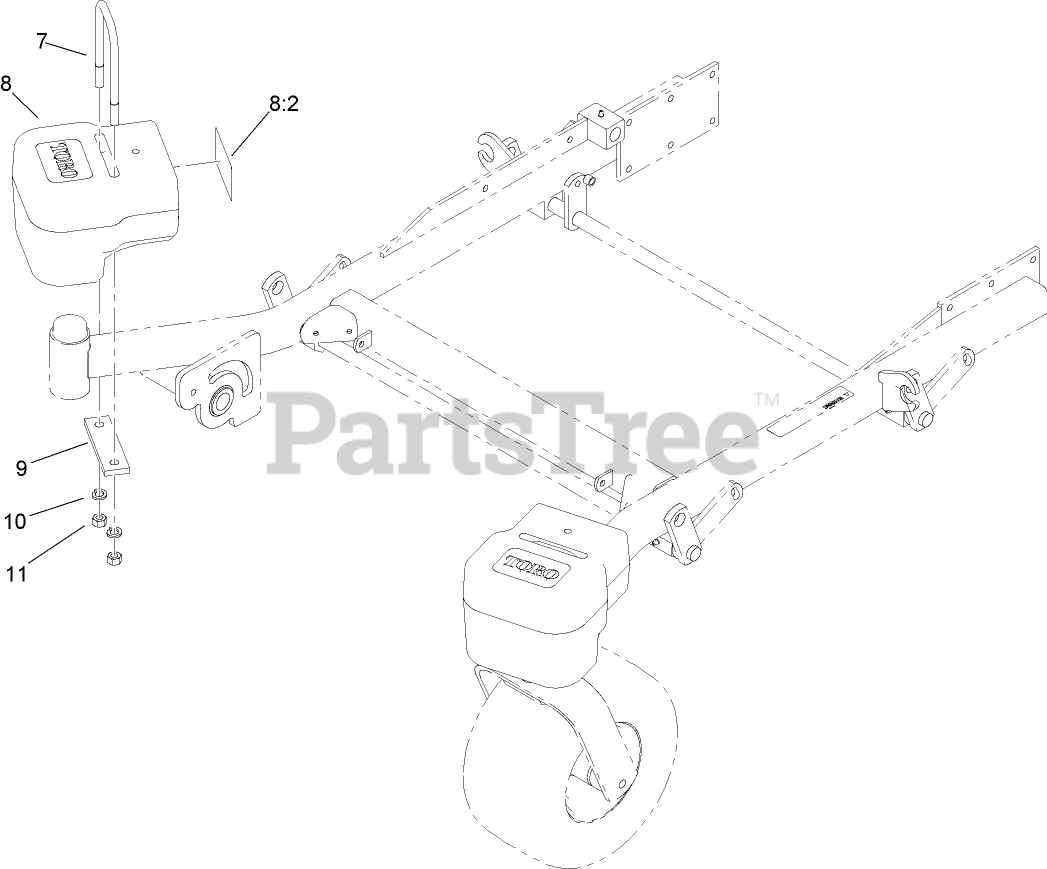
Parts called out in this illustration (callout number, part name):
7	U-BOLT
8	WEIGHT ASM
8:2	DECAL-WARNING
10	WASHER-LOCK
11	NUT-HH
